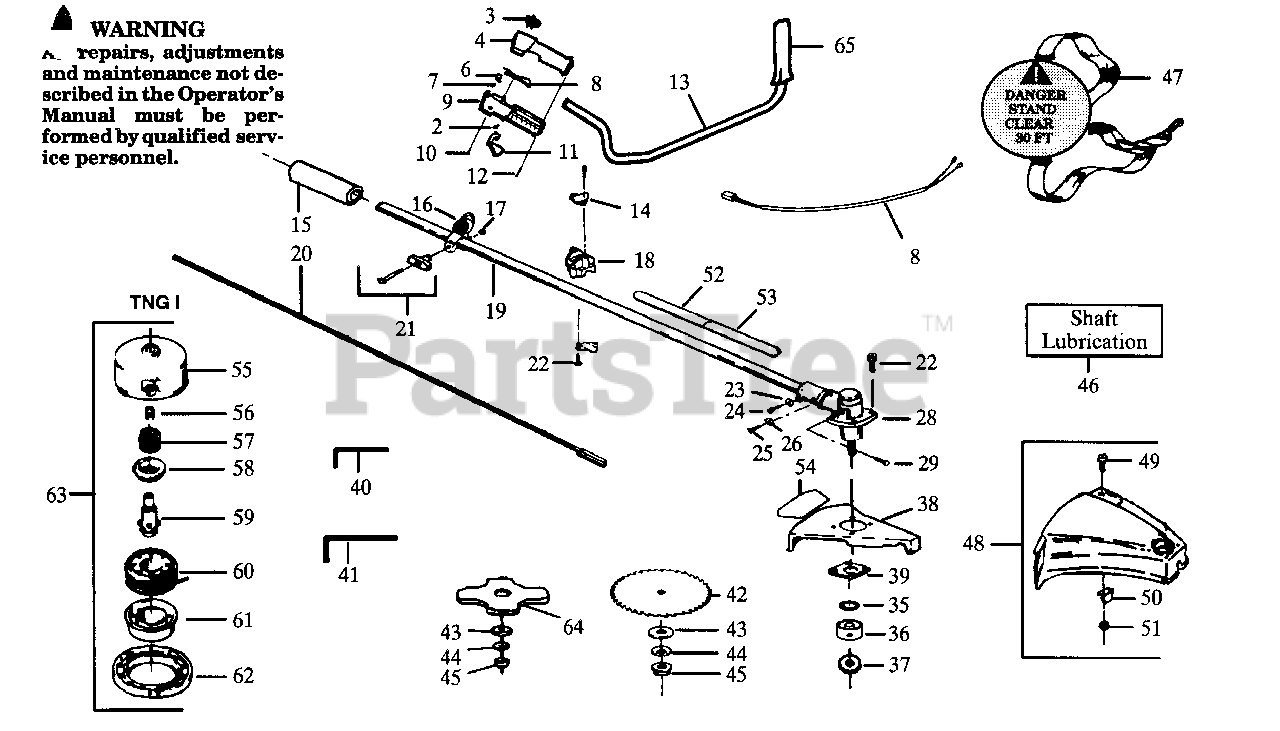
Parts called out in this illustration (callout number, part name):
1	Wire Harness Ass'y.
2	Trigger Spring
3	Rocker Switch
4	Throttle Hsg.-Left
6	Throttle Lock
7	Spring
8	Throttle Lockout
9	Throttle Hsg.-Right
11	Throttle Trigger
13	Handlebar
14	Handlebar Bracket
15	Drive Shaft Pad
16	Clamp Harness Ass'y.
18	Handlebar Clamp
19	Drive Shaft Housing
20	Drive Shaft
21	"T" Handle Ass'y.
22	Screw, Use w/Plastic Shield
22	Screw, Use w/Metal Shield
23	Lockwasher
26	Lockwasher
28	Gear Box Ass'y.
36	Dust Cup
37	Grass Washer
38	Shield-Metal
39	Shield Retention Plate
40	Hex Wrench (5/32)
41	Hex Wrench (3/16)
42	Brush Blade
44	Washer
46	Shaft Lubrication
47	Shoulder Strap
48	Shield Kit Ass'y. (Incl. 49-51)
50	Line Limiter
51	Locknut
52	Decal-Shaft Warning (Upper)
53	Decal-Shaft Warning (Lower)
54	Decal-Blade Direction (Not a serviceable part)
55	Hub Ass'y.
56	Line Saver
58	Cap-Spring
59	Drive Gear
60	Spool w/Line
61	Release Button
63	Cutting Head Ass'y. (Incl. 55-62)
64	4-Point Blade (Optional)
65	Grip-Left
